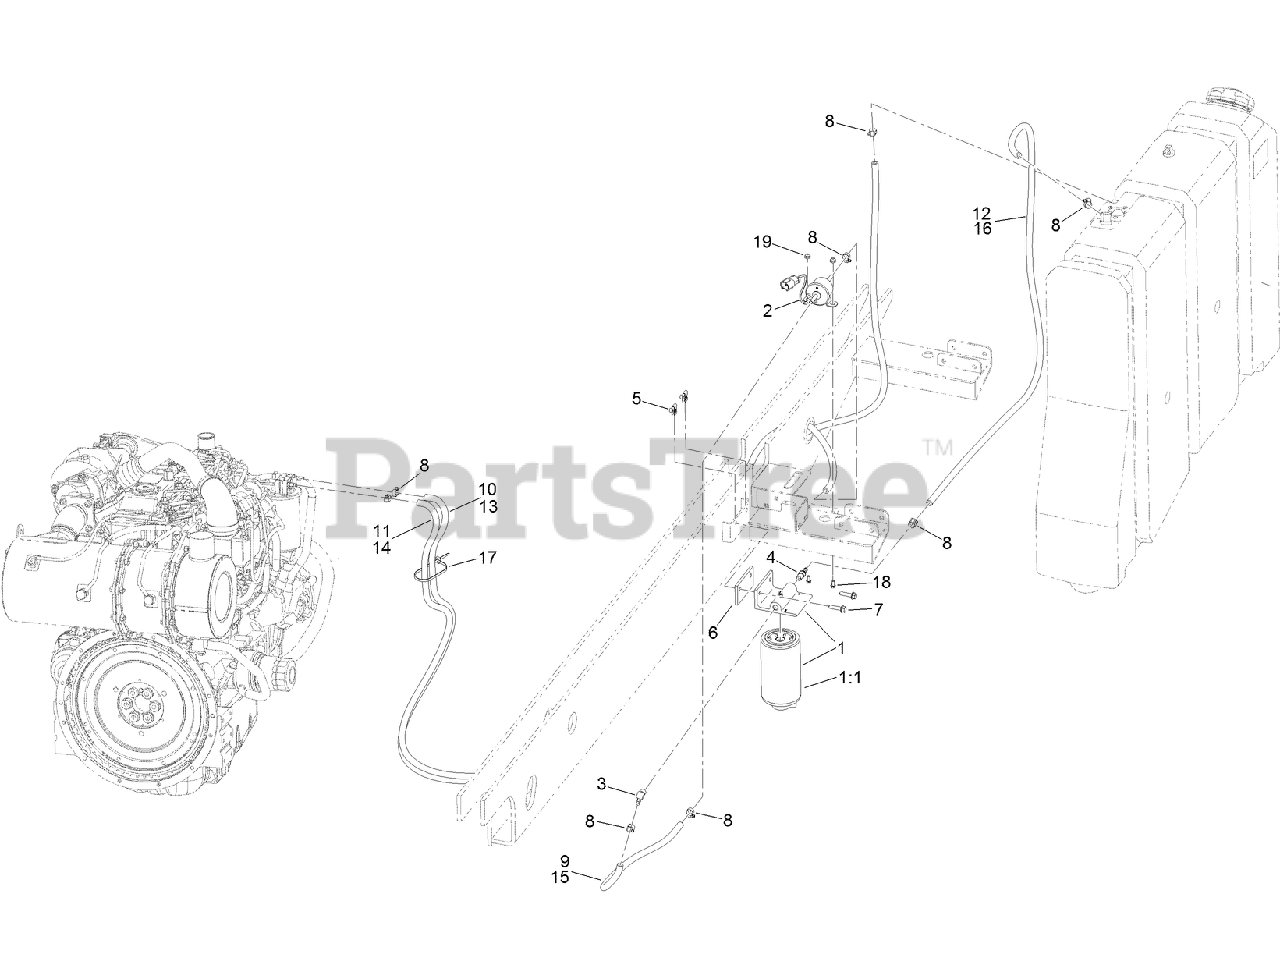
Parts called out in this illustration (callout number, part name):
1	SEPARATOR FILTER ASM
1:1	FILTER-FUEL/WATER SEPARATOR
2	PUMP-FUEL, ELECTRIC
3	FITTING-HYD, 90
4	FITTING-STRAIGHT
5	NUT-CLIP, U
6	PLATE-SPACER
7	SCREW-HHF
8	CLAMP-WORM
9	HOSE-FUEL
10	HOSE-FUEL
11	HOSE-FUEL
12	HOSE-FUEL
13	CONDUIT-FUEL LINE, SPLIT
14	CONDUIT-FUEL LINE, SPLIT
15	CONDUIT-FUEL LINE, SPLIT
16	CONDUIT-FUEL LINE, SPLIT
17	TIE-CABLE
18	SCREW-HHF
19	NUT-HF
